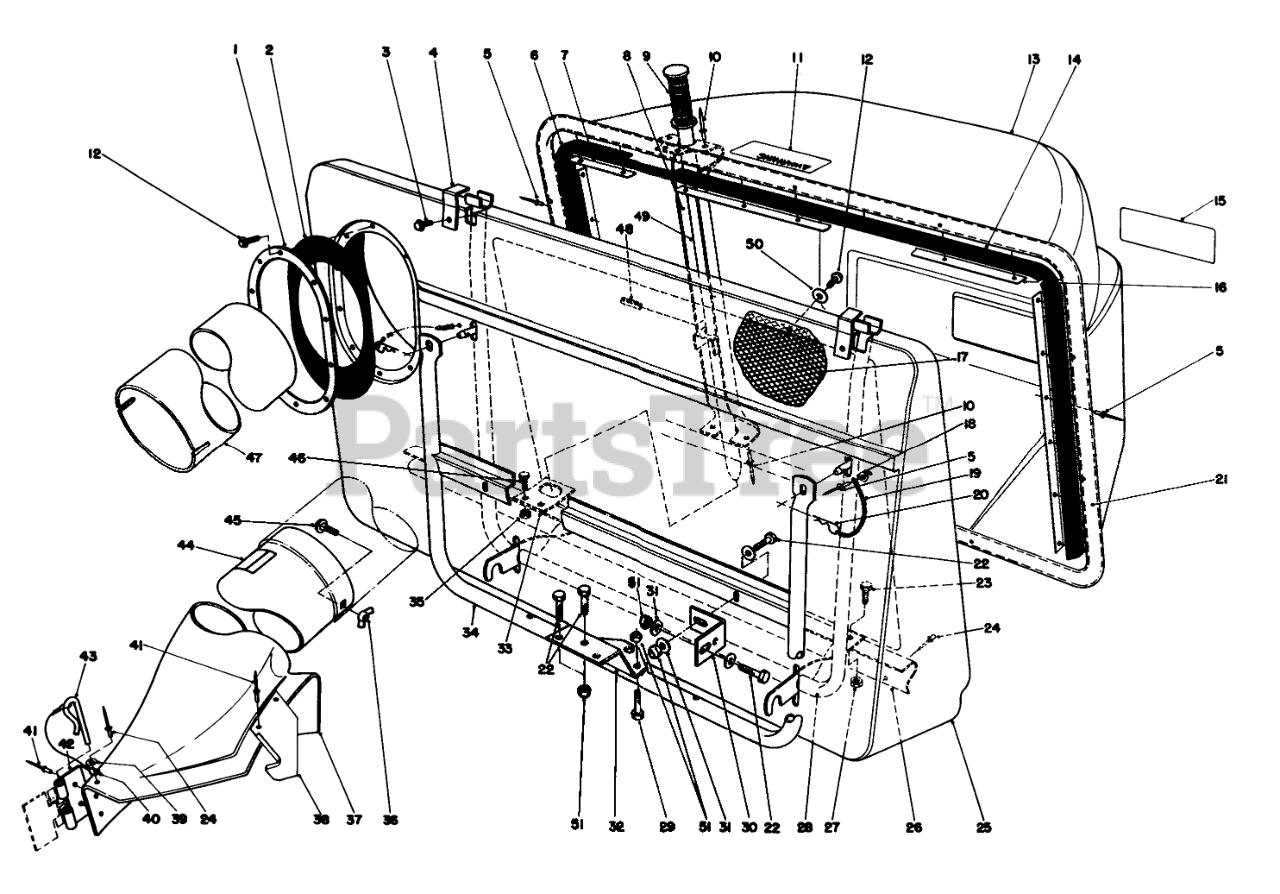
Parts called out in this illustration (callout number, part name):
1	RING-RETAINING
2	RING-RETAINER, RUBBER
3	SCREW-HWH
4	RETNR PIVOT BRKT
6	RH BAG SEAL
7	RETNR TOP EXT.
8	DUMP HDLE CHANL WA
11	Decal Warning
12	SCREW-HWHTF
13	REAR GRASS BASKET
14	Seal-Bag LH.
15	EASY EMPTY BAG DECAL
16	BAG RETNR EXT.
17	Screen Bag
18	WASHER
19	10 LINK CHAIN W/O HOOK
20	PIN-HAIR
21	BAG SUPT ASM FRM
22	SCREW-HH
23	SCREW-HH
24	RIVET-BLIND
25	Bag Front
26	FRAME SUPT BRKT B
27	NUT-LOCK, CONE
28	Bag Frame
29	SCREW-HH
30	MTG BRACKET
31	WASHER-PLAIN
32	MTG PLATE B
33	Hanger-Frame Lower
34	BAG SUPPORT WA
35	NUT-LOCK, CONE
36	NUT-WING SPECL
37	Chute Assembly (Incl. Ref. #24, 38-44)
38	CHUTE SUPT BRKT
39	WASHER-PLAIN
40	LANYARD
41	RIVET-BLIND
42	BRACKET-MOUNTING, CHUTE
43	PIN-LOCKING, CHUTE
44	DECAL-DANGER
45	BOLT-CARR
46	SCREW-HH
47	TUBE(ROUND&LONG)
48	PIN-ROLL
49	DUMP HANDLE ASM
50	WASHER-FLAT
51	NUT-LOCK, NI
